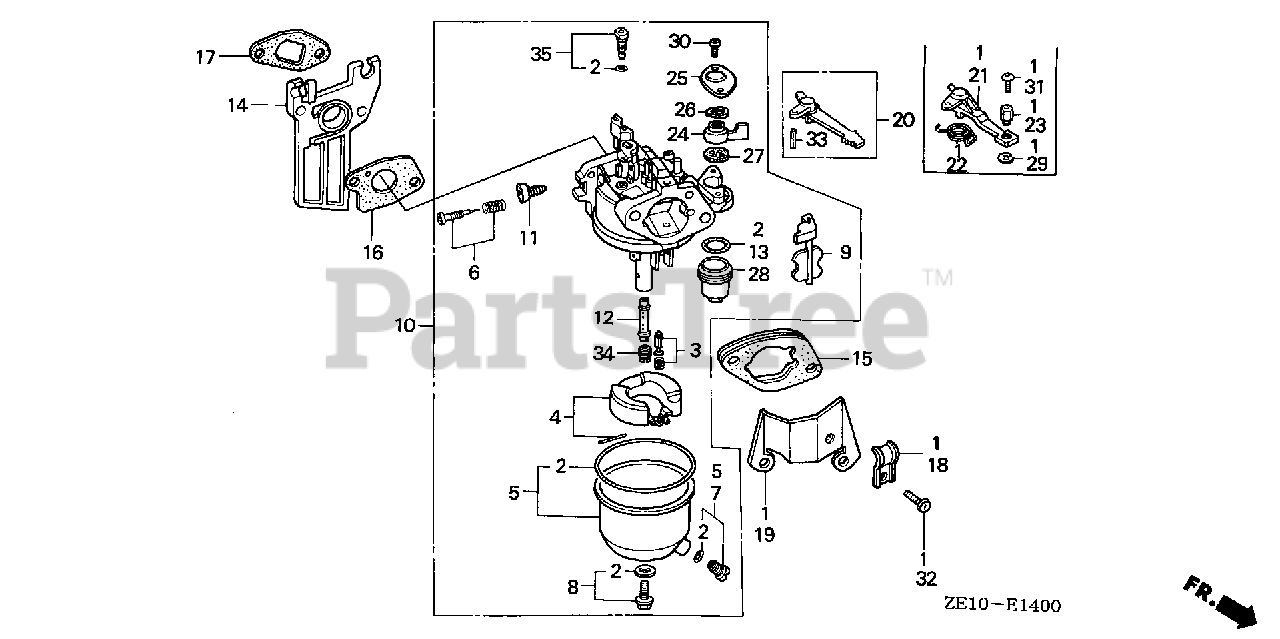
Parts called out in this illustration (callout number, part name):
2	GASKET SET (CARBURETOR NO.)
3	VALVE SET, FLOAT (SEAT NOT INCLUDED)
5	CHAMBER SET, FLOAT
6	SCREW SET, PILOT
7	SCREW SET, DRAIN
8	SCREW SET
10	CARBURETOR ASSY. (BE05C B) Use up to Engine SN 1378034.
10	CARBURETOR ASSY.
11	SCREW, THROTTLE STOP
12	NOZZLE, MAIN
13	GASKET, FUEL STRAINER CUP
14	INSULATOR, CARBURETOR
15	SPACER, CARBURETOR
16	GASKET, CARBURETOR
17	GASKET, INSULATOR
20	LEVER, CHOKE (STD)
24	LEVER, VALVE
25	PLATE, LEVER SETTING
26	SPRING, PETCOCK LEVER (CARBURETOR NO.)
27	GASKET, PETCOCK (CARBURETOR NO.)
28	CUP, FUEL STRAINER
30	SCREW, PAN (3X8)
30	SCREW, PAN (3X8) (CARBURETOR NO.)
33	PIN, SPRING (2X12)
34	JET, MAIN (#62)
34	JET, MAIN (#65)
34	JET, MAIN (#68)
35	JET SET, PILOT (#35)
